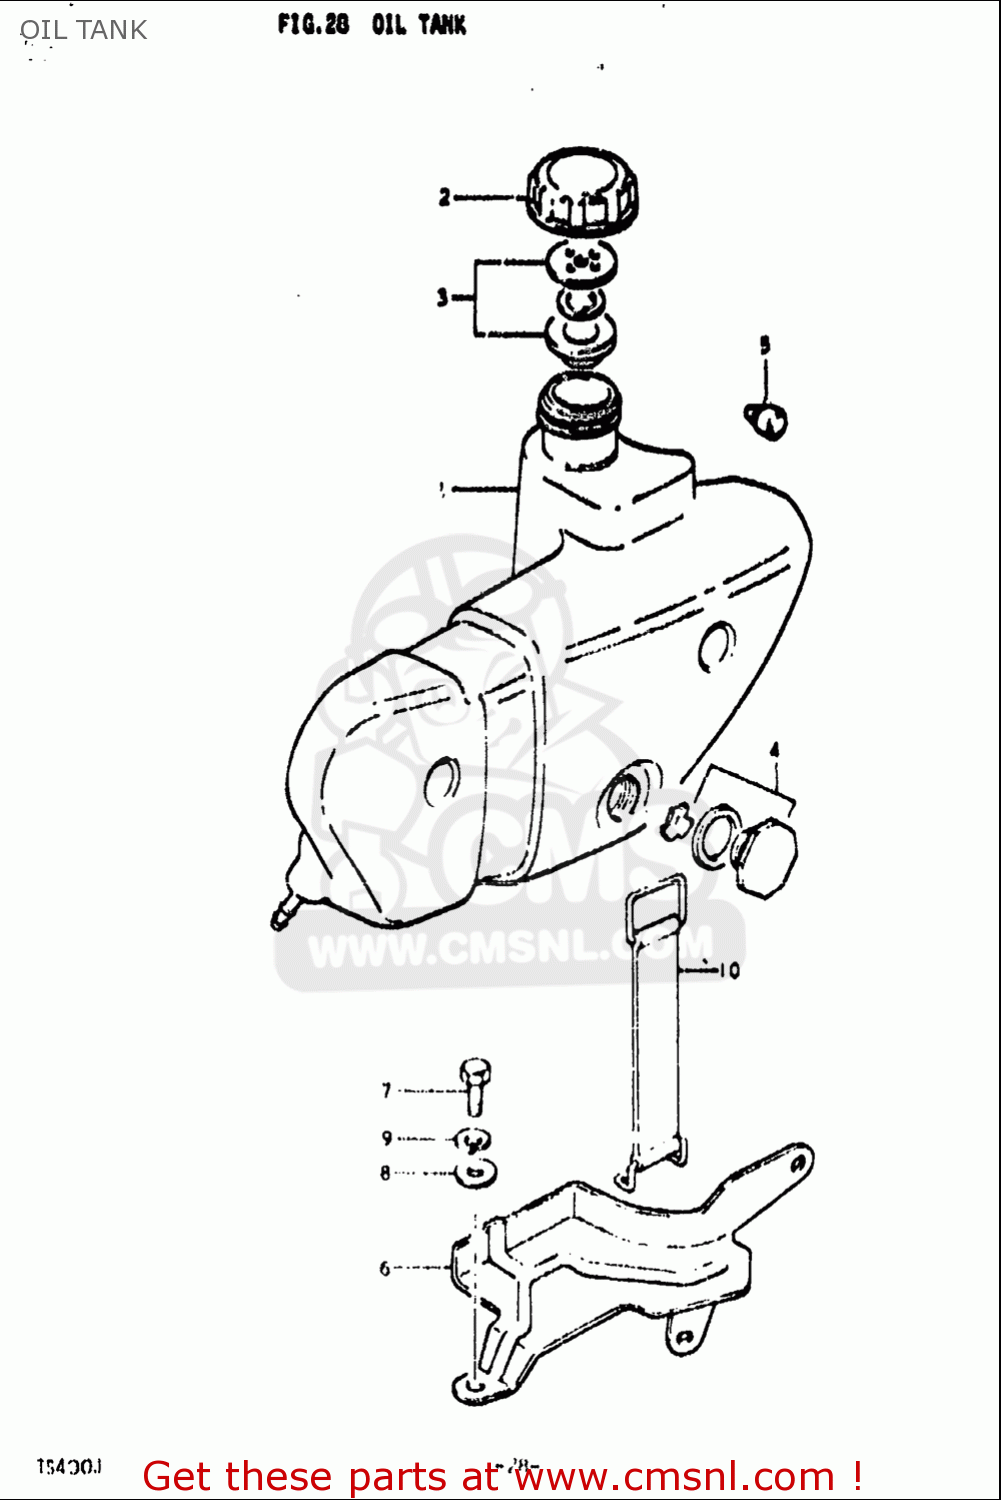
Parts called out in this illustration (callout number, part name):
2	CAP,OIL TANK
3	GASKET SET (NAS)
4	LENS SET,OIL LEVEL
6	HOLDER, OIL TANK
7	BOLT
8	WASHER
9	WASHER,LOCK
